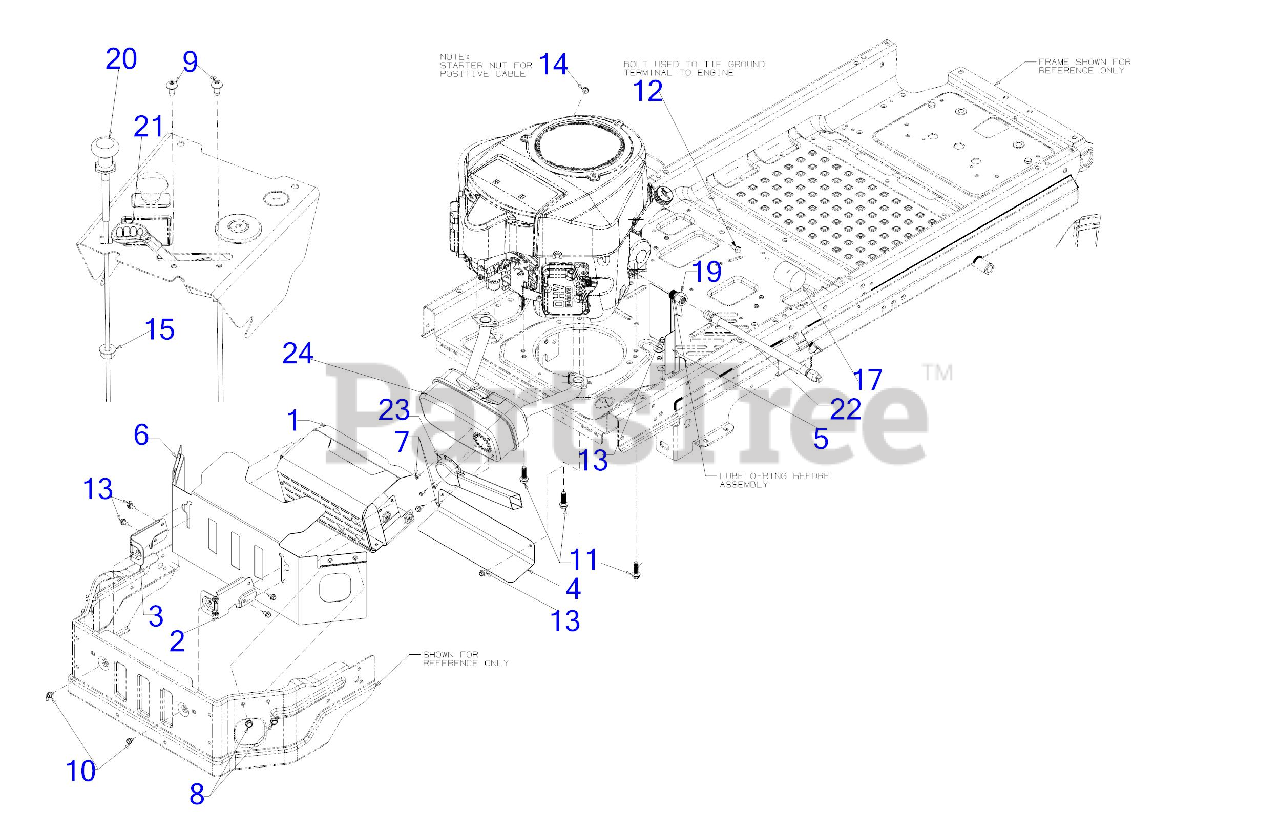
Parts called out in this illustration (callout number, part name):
4	LOWER HEAT SHIELD
5	ENGINE HEAT SHIELD
6	MUFFLER BUMPER SHIELD
7	HEX SCREW WASHER HD #8-18 x 0.500
8	SCREW 5/16-18 x .750
9	SCREW 1/4-20 x .5
10	SCREW 1/4-20 x .375
11	SCREW 3/8-16 X1.250
12	SCREW M8-1.25 x 16 Gr8.8
13	SCREW 1/4-20X.625
14	FLANGE LOCK NUT
15	HEX FLANGE NUT
19	OIL DRAIN FITTING
20	40.5" CHOKE CABLE
21	THROTTLE CABLE 38.5"
22	OIL DRAIN HOSE
23	MUFFLER DEFLECTOR
24	EXHAUST MUFFLER
